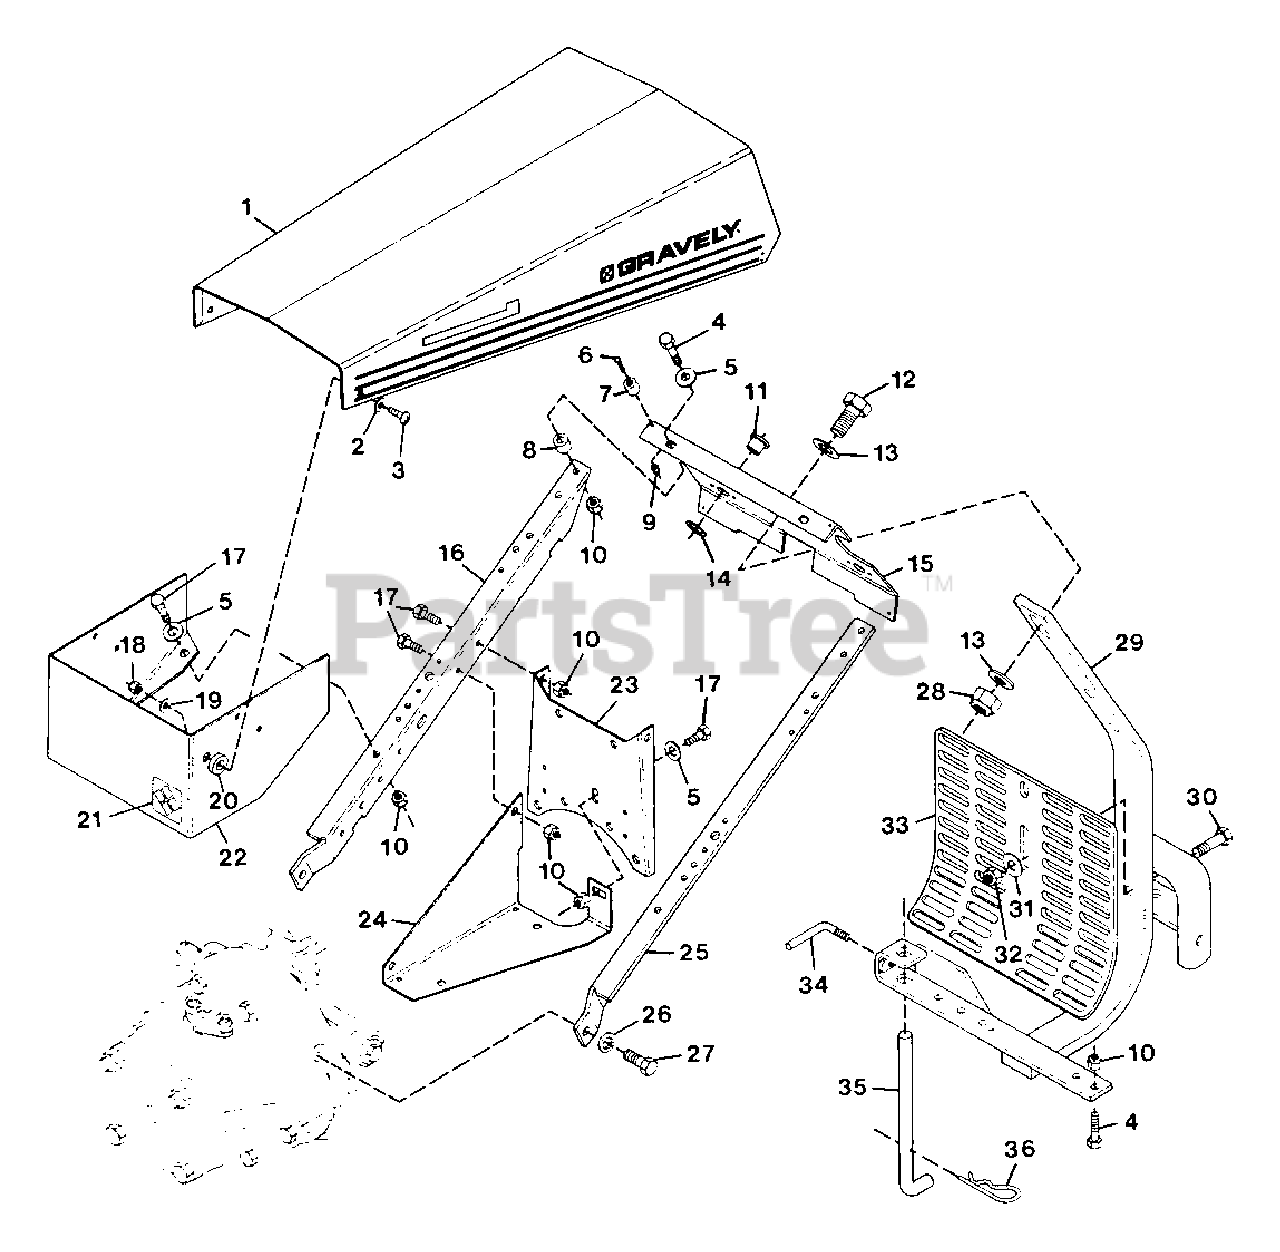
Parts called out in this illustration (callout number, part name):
1	Assembly, Hood
2	Washer, Flat .281x.625x.065
3	Screw, Mach. 1/4-20x1.00 PHD
4	Bolt, Hex 3/8-16x1.50
5	Washer, Flat .406x.812x.065 (Manual)
5	Washer, Flat .406x.812x.065 (Electric)
6	Screw, Mach. 6-32x.625 PHD
7	Bumper
8	Bushing, Reverse Idler
9	Nut, Mach. Lock 6-32
10	Nut, Lock 3/8-16 (Manual)
10	Nut, Lock 3/8-16 (Electric)
11	Bushing, .513x.750x.625
12	Bolt, Hex 5/8-11x2.00
13	Washer, Flat .656x1.250x1.00
14	Ring, Retaining
15	Plate, Silk Screen (Manual)
15	Plate, Silk Screen (Electric)
16	Support, Handlebar R.H.
17	Bolt, Hex 3/8-16x.875 (Manual)
17	Bolt, Hex 3/8-16x.875 (Electric)
18	Nut, Lock 1/4-20
19	Washer, Flat .313x.875x.065
20	Bushing, Hood
21	Decal
22	Support, Hood
23	Bracket
24	Tray, Battery (Electric)
25	Support, Handlebar L.H.
26	Washer, Lock 1/2 Reg.
27	Bolt, Hex 1/2-13x1.00
28	Nut, Lock 5/8-11
29	Weldment, Hitch 8 H.P.
30	Bolt, Hex 1/2-13x1.50
31	Washer, Flat .531x1.250x.100
32	Nut, Lock 1/2-13
33	Guard, Engine
34	Handle, Adjusting
35	Stand, Kick
36	Pin, Hair
NS	Decal, 8
NS	Decal, Side Stripe
NS	Decal, Gravely
NS	Decal, 6 Lead
NS	Decal, 8 Lead
NS	Decal, Professional
